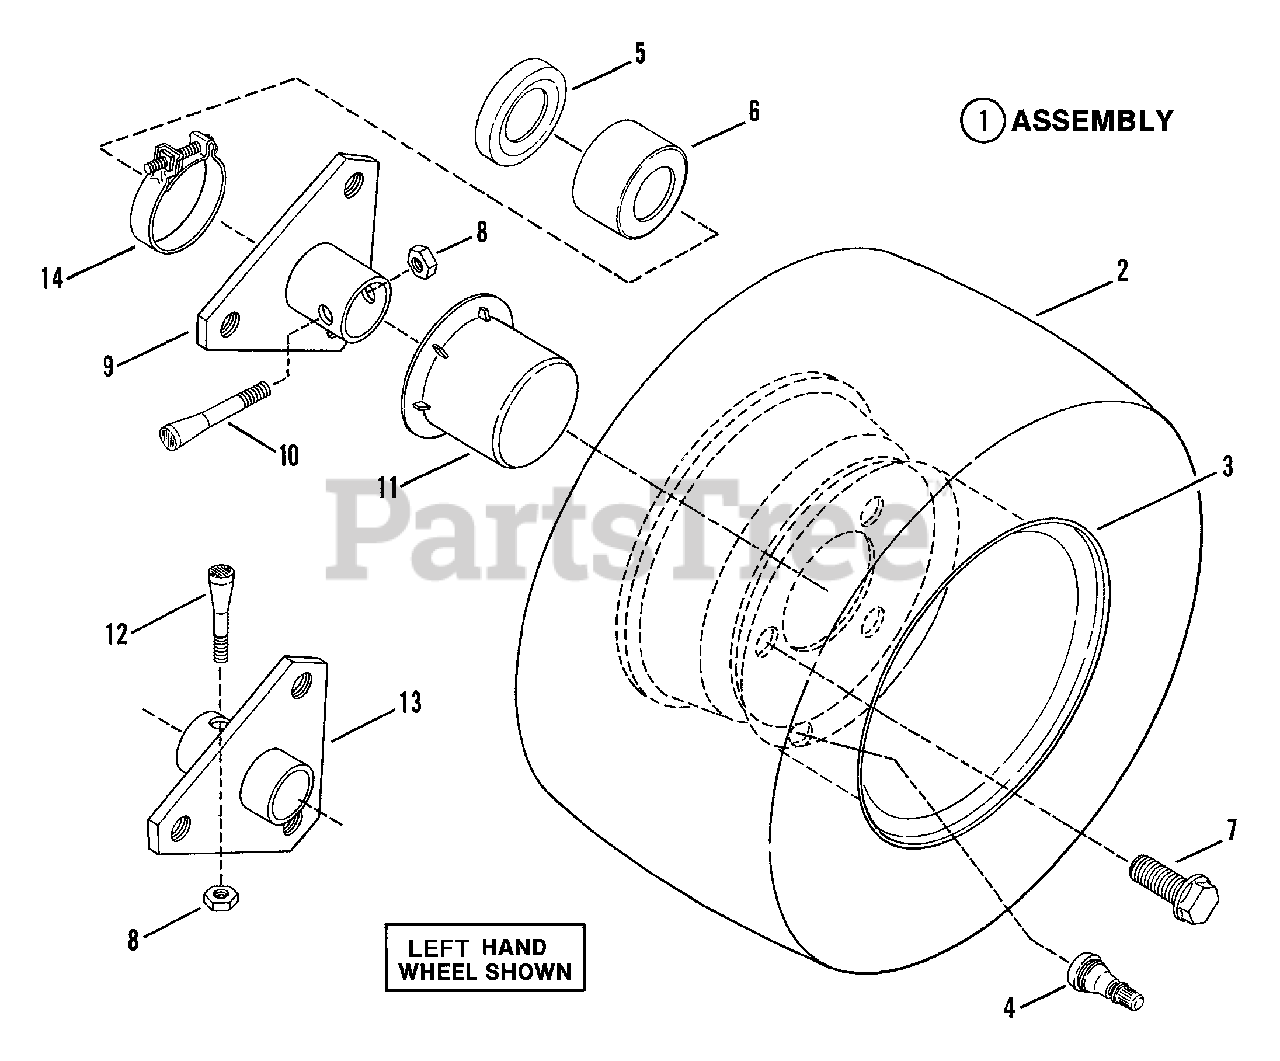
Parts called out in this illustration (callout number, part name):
1	ASSEMBLY, Rear Tire & Rim (41" Deck)
2	TIRE, 18-8.50x8
3	RIM, 8x7
4	VALVE, Air (Snap-in)
5	SEAL, Oil (Left Hand)
6	CAP, Seal, (Left Hand)
7	BOLT, 1/2-20x3/4" Lug
8	NUT, 5/16-24, Lock
9	HUB, Rear Wheel, Left Hand 1.126" ID
10	BOLT, 5/16-24x2", Tapered, Left Hand
11	HUB-CAP
12	BOLT, 5/16-24x1-5/8", Tapered, Right Hand
13	HUB, Rear Wheel, Right Hand .75" ID
14	CLAMP
